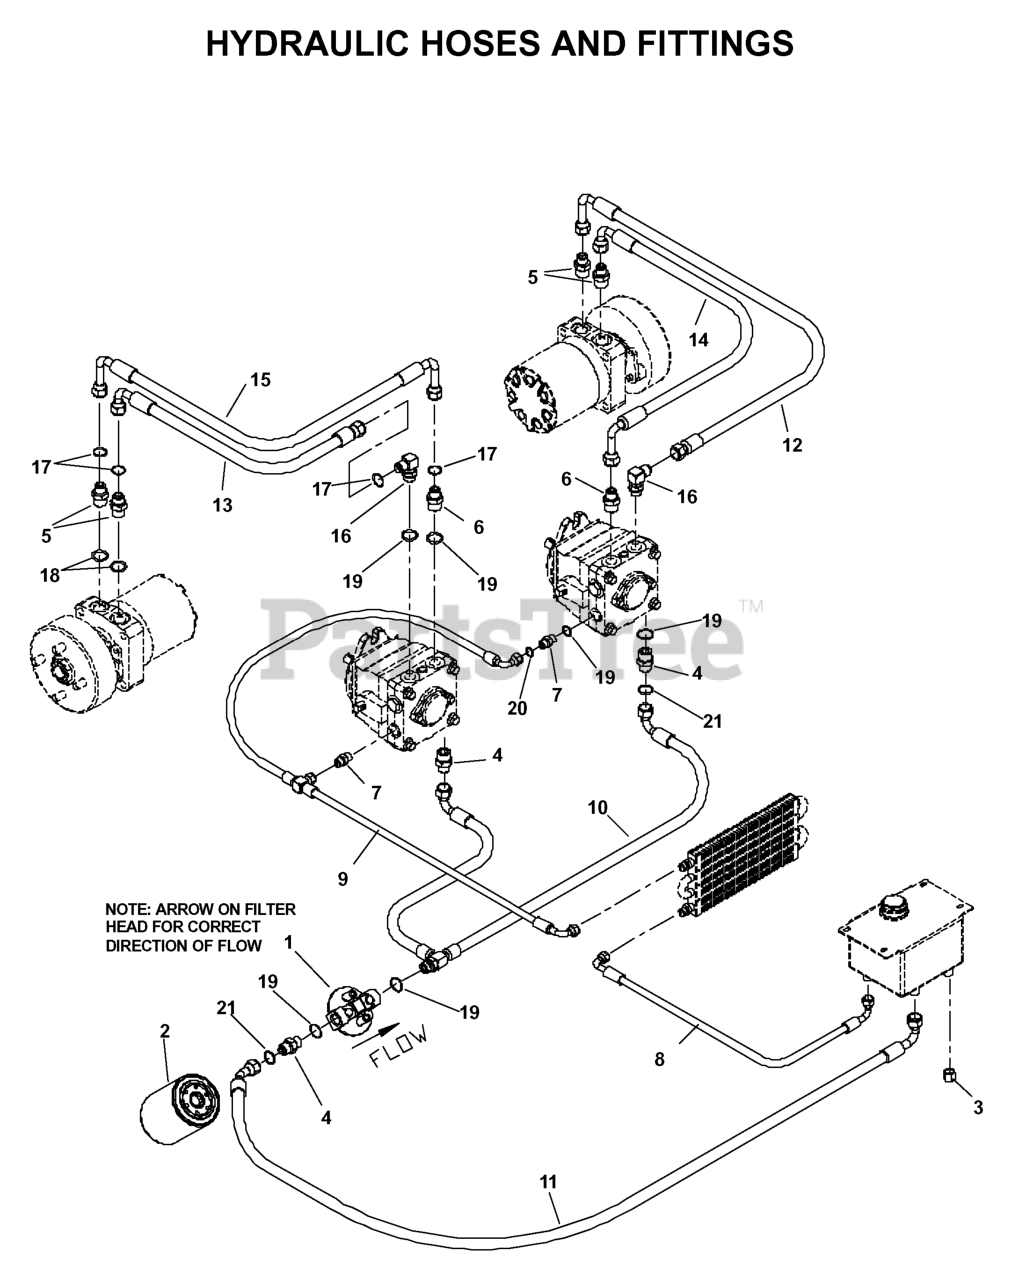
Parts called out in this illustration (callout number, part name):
1	FILTER HEAD
2	HYDRAULIC OIL FILTER
3	NUT 9/16-18 JIC CAP
4	FITTING, STRAIGHT F6400-8-8-0
